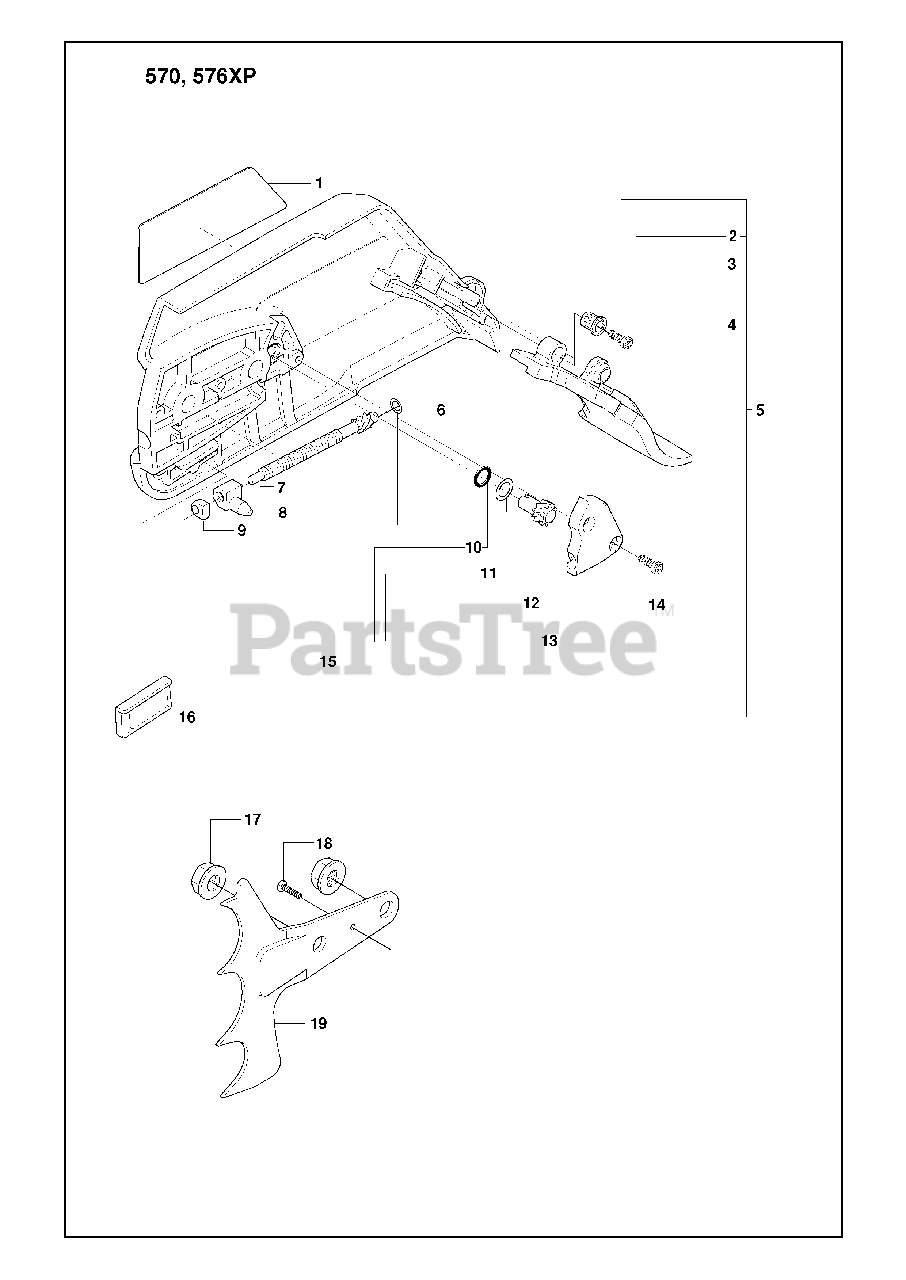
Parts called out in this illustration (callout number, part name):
5	CHAIN BRAKE COVER
5	CLUTCH COVER ASSY
7	ADJUSTER
12	RP ADJUSTER
15	KIT-CHAIN TENSIONER
16	CHAIN GUIDE
17	NUT M8 FLANGE
19	SPIKE OUTER
